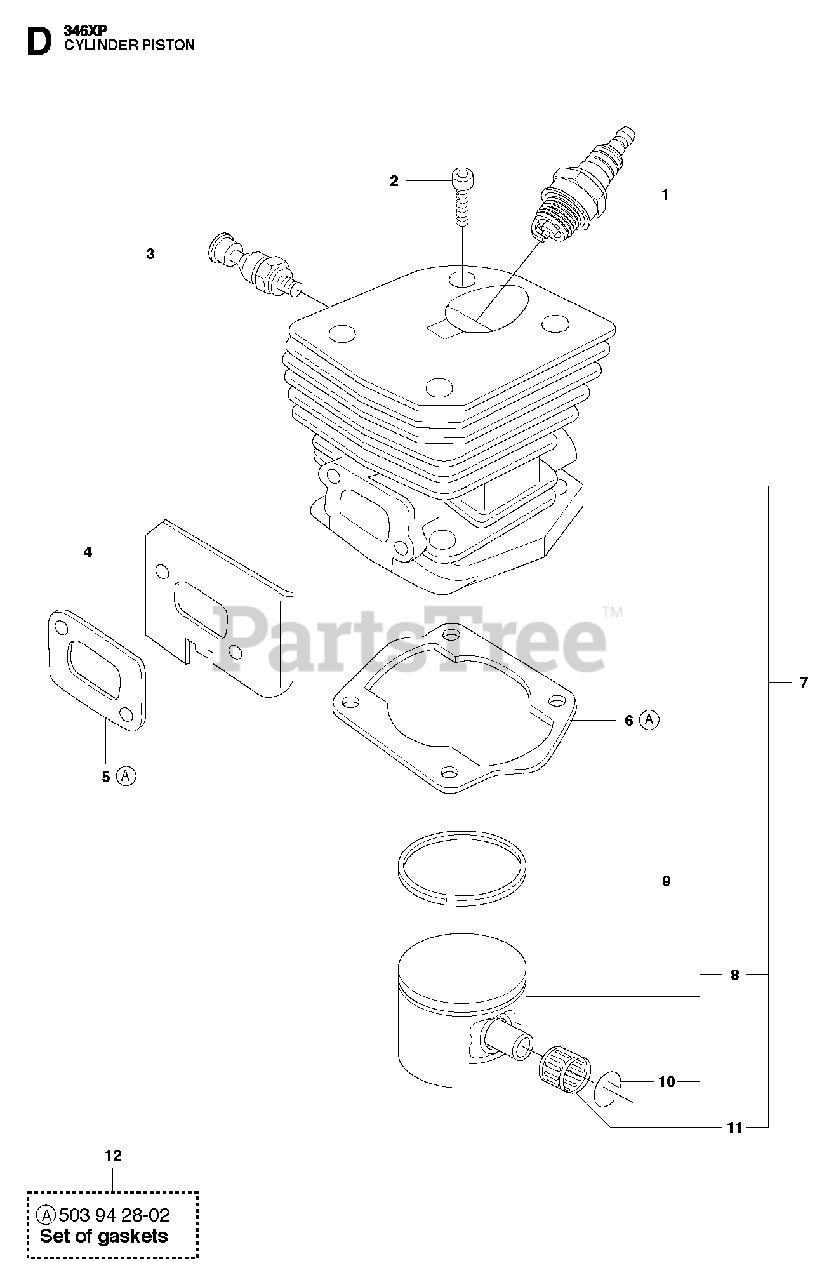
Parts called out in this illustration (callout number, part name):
1	SPARK PLUG RCJ7Y
2	SCREW MC6S 5X25
3	DECOMPRESSION VALVE
5	GASKET
6	GASKET
7	CYLINDER
8	PISTON ASSY
9	PISTON RING
10	LOCKING RING
11	SUPPORT BUSHING
12	GASKET SET
